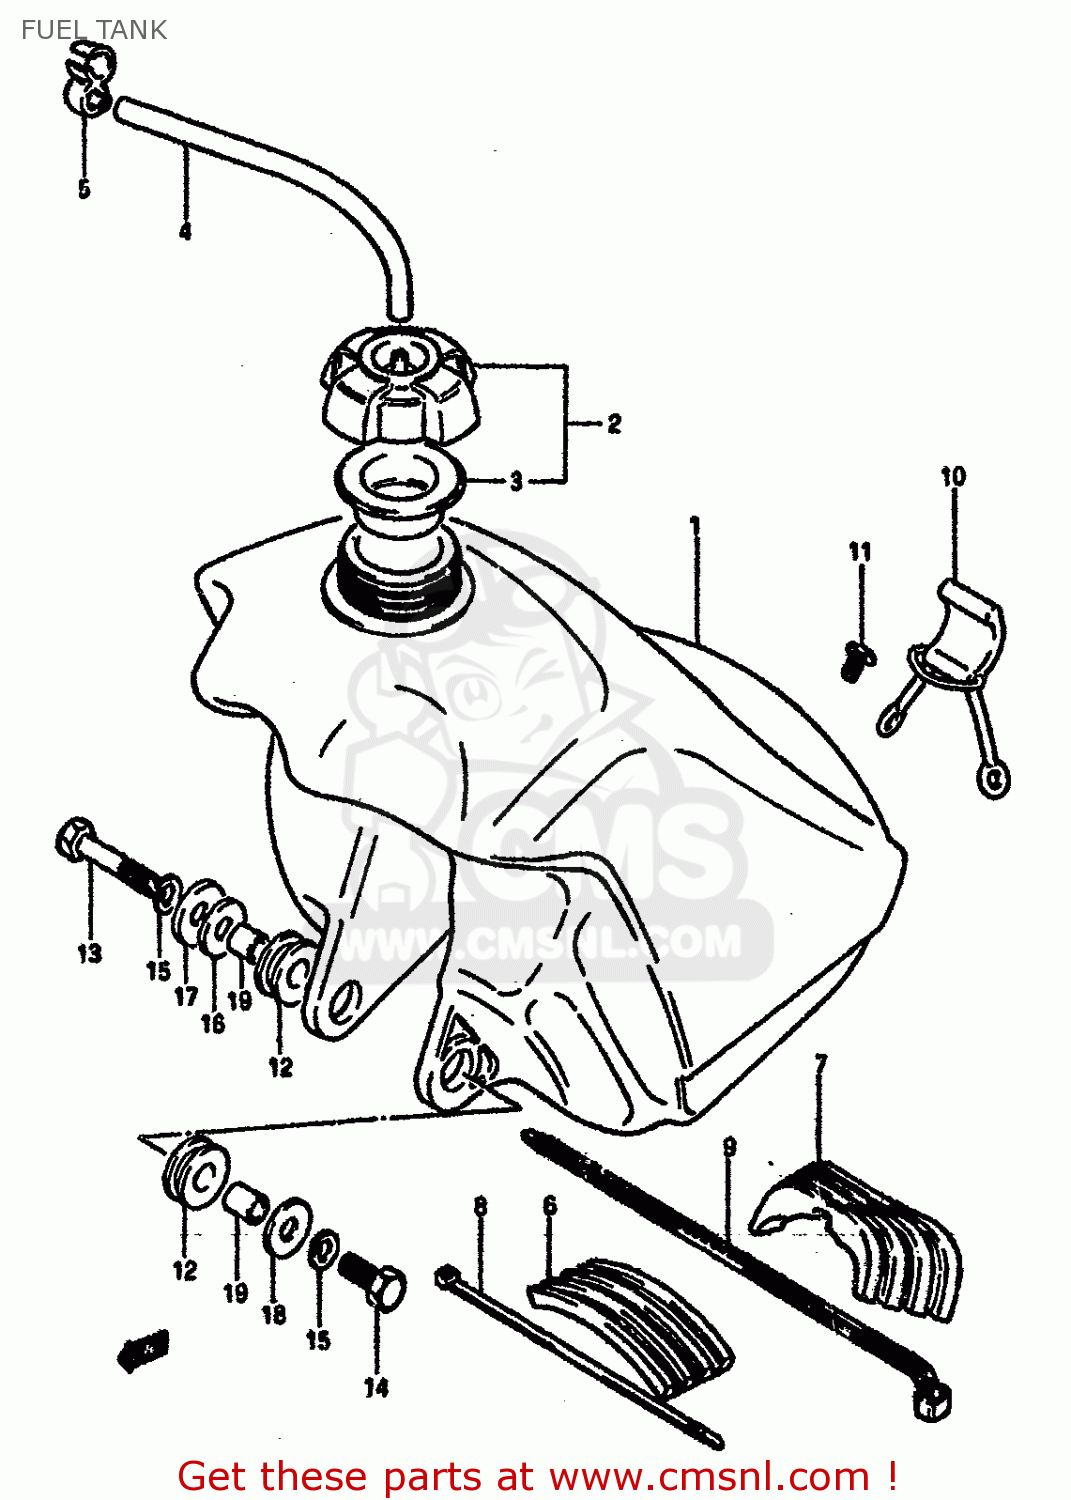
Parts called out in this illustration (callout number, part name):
1	TANK SET,FUEL
2	CAP SET,FUEL TANK
3	GASKET,FUEL TANK CAP (NAS)
4	HOSE
5	CLAMP,BREATHER HOSE
6	CUSHION,FUEL TANK UPR FR
7	CUSHION,FUEL TANK
8	CLAMP
9	CLAMP(L:250)
10	BAND,FUEL TANK RR
11	SCREW (6X15)
12	CUSHION
13	BOLT
14	BOLT (8X30)
15	LOCK WASHER
16	WASHER(8.5X26X1.2)
17	WASHER
18	WASHER
19	SPACER (8.8X12X13.5)
